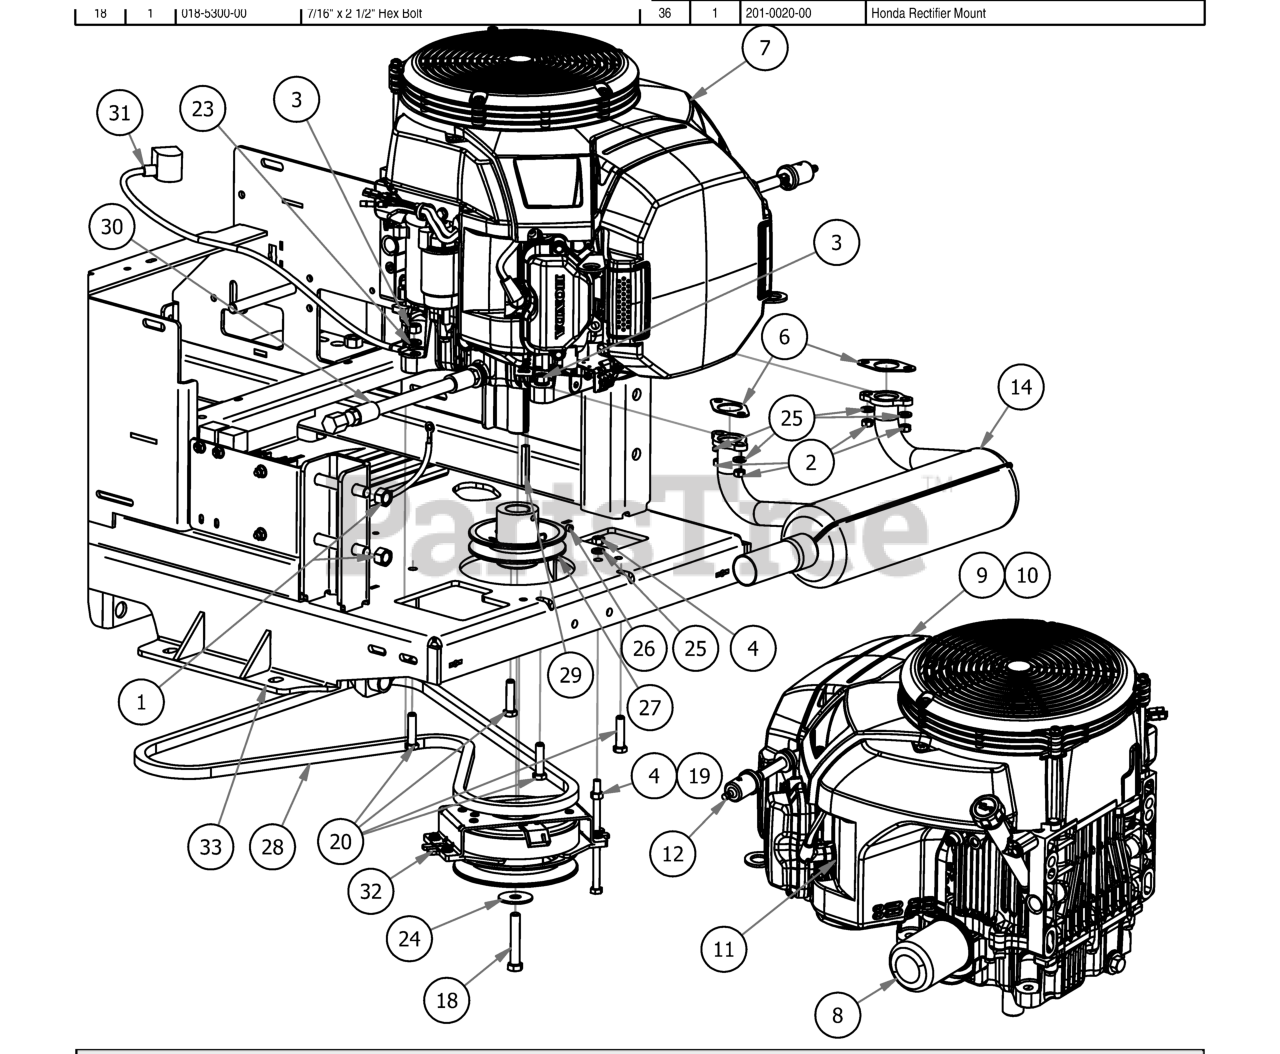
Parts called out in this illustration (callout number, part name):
1	1/2" Center Lock Nut
2	M8-1.25 Zinc Nut
3	3/8" Hex Nut
5	1/4-20 Hex Flange Nuts Zinc w/Serrations
6	Exhaust Gasket
7	2019 Honda Engine
8	Oil Filter
9	Pre-Cleaner
10	Air Cleaner Element
11	Spark Plug
12	Fuel Flilter
13	Regulator Rectifier for Honda Engine
14	2019 Honda Maverick Muffler
15	M6-1.0 X 16MM Hex Bolt
16	1/4" x 1/2" BS C/S 18-8 SS
17	1/4-20 x 1 GR 5 hex bolt zinc
18	7/16" x 2 1/2" Hex Bolt
19	5/16-18 x 5-1/2 GR 5 Hex Bolt
20	3/8 x 1.5" Bolt
21	1/2-13 x 3 1/2 GR 5 Hex Bolt
22	1/4" Lock Washer
23	3/8" Lock Washer
24	1/2" Belleville Washer
25	5/16" Lock Washer
26	5/16 Set Screw
27	4 3/4 Motor Pulley
28	75.8" Pump Belt
29	1/4 x 2 Square key Stock
30	Honda Oil Drain
31	Ground Cable
33	2018 Maverick Frame
34	Relay Terminal
35	Wiring Harness
36	Honda Rectifier Mount
